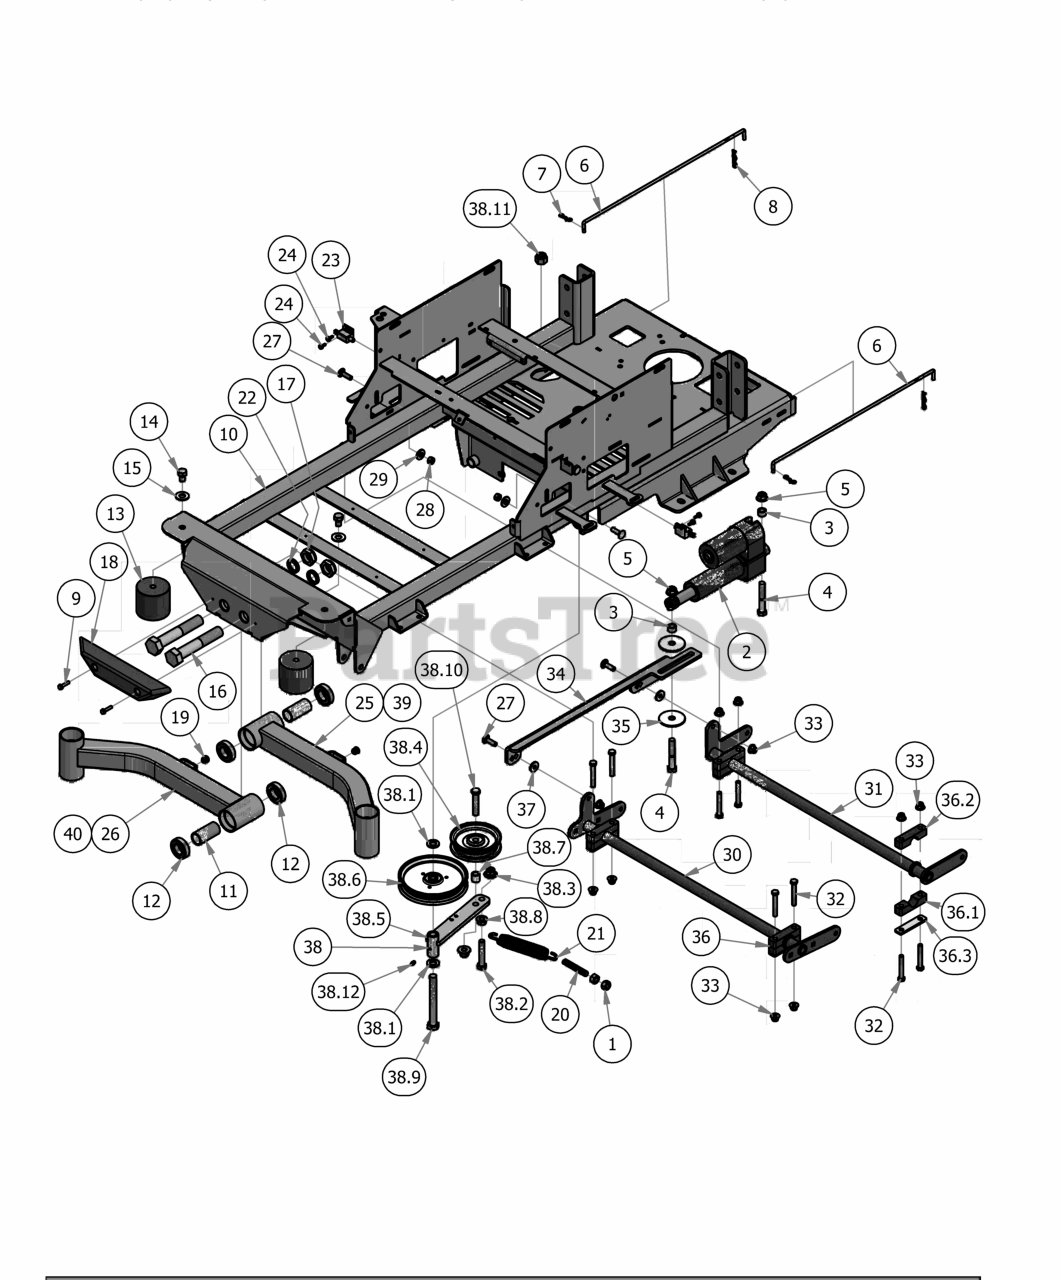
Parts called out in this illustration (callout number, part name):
1	1/2" Hex Nut
3	1/2 x 1/2 Spacer
4	1/2 x 2-3/4 Hex Bolt
5	1/2-13 Nylon Insert Flange Nut Zinc Orange Nylon
6	ZT Neutral level rod 2011
8	Neutral Rod Clip
9	1/4 x 1 Hex Head Tek screw
10	2018 Maverick Frame
11	2016 Front Bearing Spacer
12	Caster Bearing 2016 - 1641 Bearing
13	Vibration Mount- Red Dot
14	1/2" x 3/4" Hex Bolt
15	1/2" Washer (Grade 8)
16	1-14 x 5.5 Hex Bolt Grade 8 Zinc Yellow
17	1" Fine Thread 1/2 Nylock Nut
18	Front Bumper
19	5/8 Round Insert
20	All Thread-Pump Idler Tensioner
21	Deck Idler Spring
22	1" x .25" Spacer
23	Safety Switch
24	12-24x 1/2 HWH Bolt
25	2018 Maverick Suspension Arm Assembly-Left Long
26	2018 Maverick Suspension Arm Assembly-Right Long
27	3/8" x 1 1/4" Carriage Bolt
28	3/8" Hex Nut
29	3/8" Flat Washer
30	Actuator Bar Front- 2017 MZ/ZT
31	Actuator Bar Rear- 2017 MZ/ZT
32	3/8-16 x 2 1/2" Hex Bolt
33	3/8 Nylock Flange Nut
34	2017 MZ/ZT Actuator Linkage
35	Snubbing Washer
36	Pillow Block Kit
36.1	Pillow Block MZ male
36.2	Pillow Block MZ female
36.3	Pillow Block Strap
37	.360 ID Plastic Washer
38	EZT Pump Idler
38.1	.630 ID Plastic Washer
38.2	1/2" x 2 3/4" Hex Bolt
38.3	1/2-13 Nylon Flange Nut
38.4	4 3/4" Idler Pulley
38.5	Deck Idler
38.6	5-3/4 Idler Pulley-Don Dye
38.7	Spacer 3/4 OD x 1/2 ID x 3\4 Length
38.8	1/2" Flange Nut
38.9	5/8" x 5 1/2 Hex Bolt
38.10	1/2" x 3" Hex Bolt
38.11	5/8 Std NC Nylock Nut
38.12	1/4" Press in Grease Fitting
39	2018 Maverick Suspension Arm Assembly-Left Short (48" Deck Only)
40	2018 Maverick Suspension Arm Assembly-Right Short (48" Deck Only)
